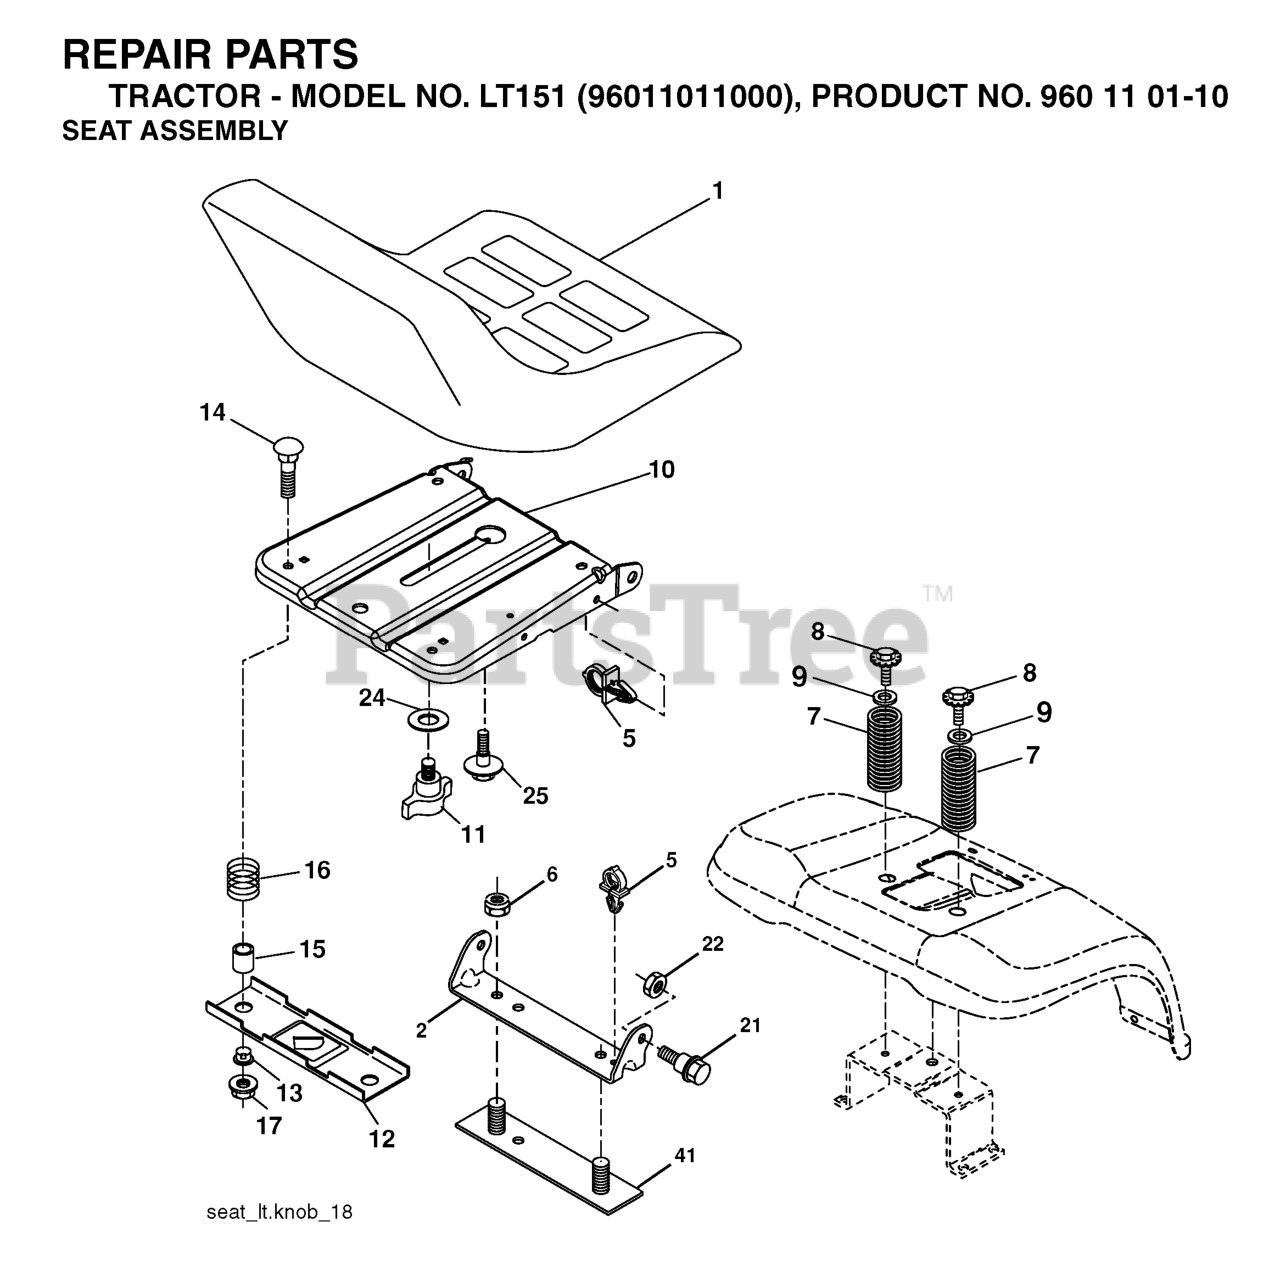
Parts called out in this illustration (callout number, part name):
1	SEAT
2	SEAT PIVOT BRKT
3	BOLT, HEX 3/8-16X1
6	NUT
7	SPRING COMPRESSION
8	SCREW 3/8-16X1
9	WASHER
10	PAN.ASM.SEAT.1SLOT
11	KNOB.SEAT.ADJ.WINGNUT
12	BRKT.MNTNG.SWITCH.SEAT.BLACK
14	BOLT.ROUND.HEAD.SQUARE.NECK
15	SPACER SPLIT 28X.96
17	NUT T
21	BOLT.SHOULDER.5/16-18
22	NUT.71038.31-18.HEX.NYLOCK
25	BOLT,SHOULD
41	STRAP
